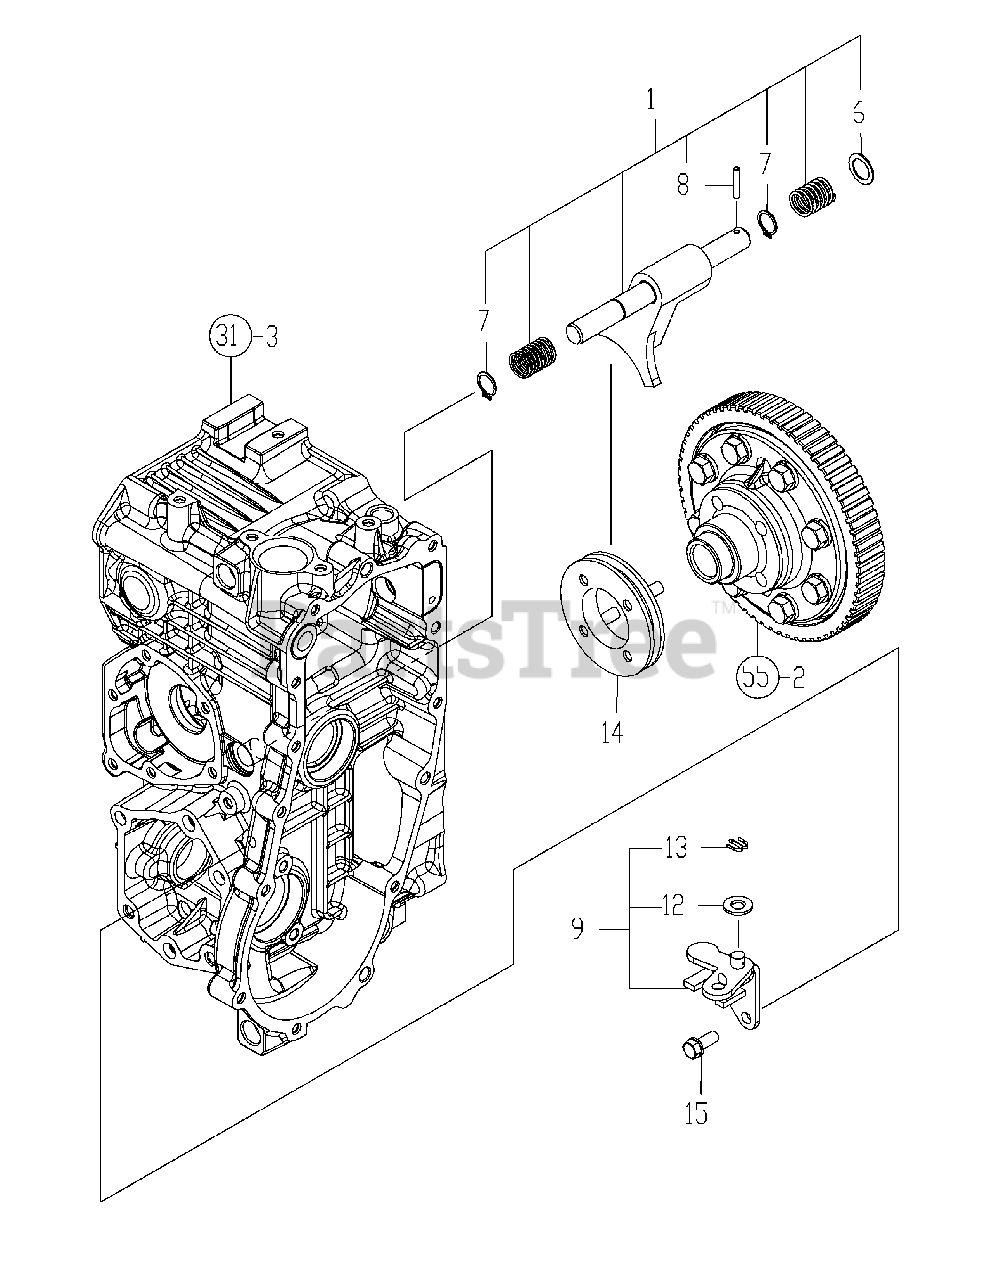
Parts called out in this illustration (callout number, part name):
1	FORK KIT, DIFF.LOCK
6	SPACER, 16.5X24X1
8	PIN, 4.0A X 25
9	FULCRUM KIT, DIFF.
14	SLIDER, DIFF.LOCK
